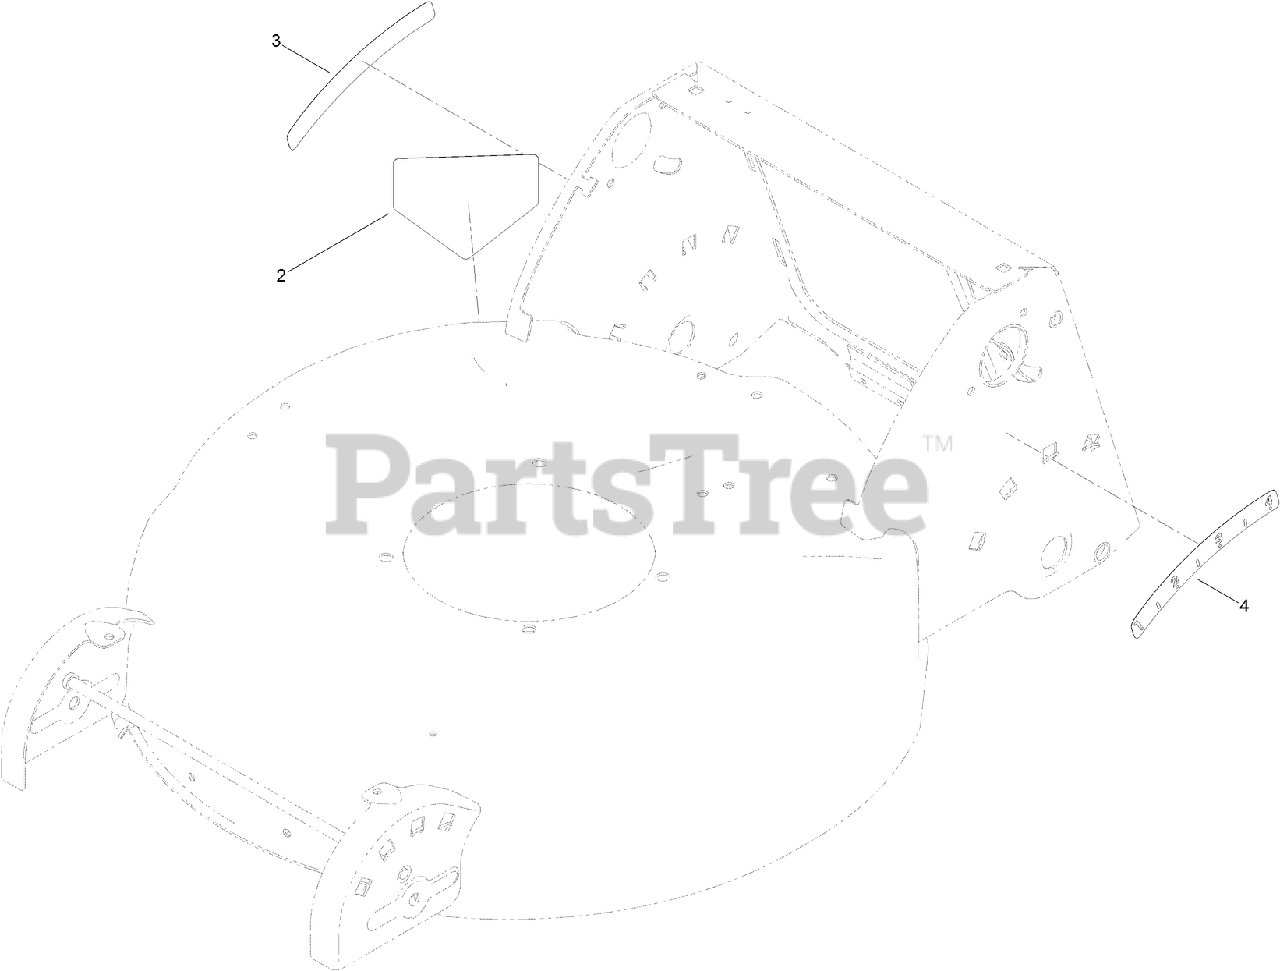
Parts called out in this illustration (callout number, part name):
2	DECAL-DANGER
3	DECAL-HOC, RH
4	DECAL-HOC, LH
